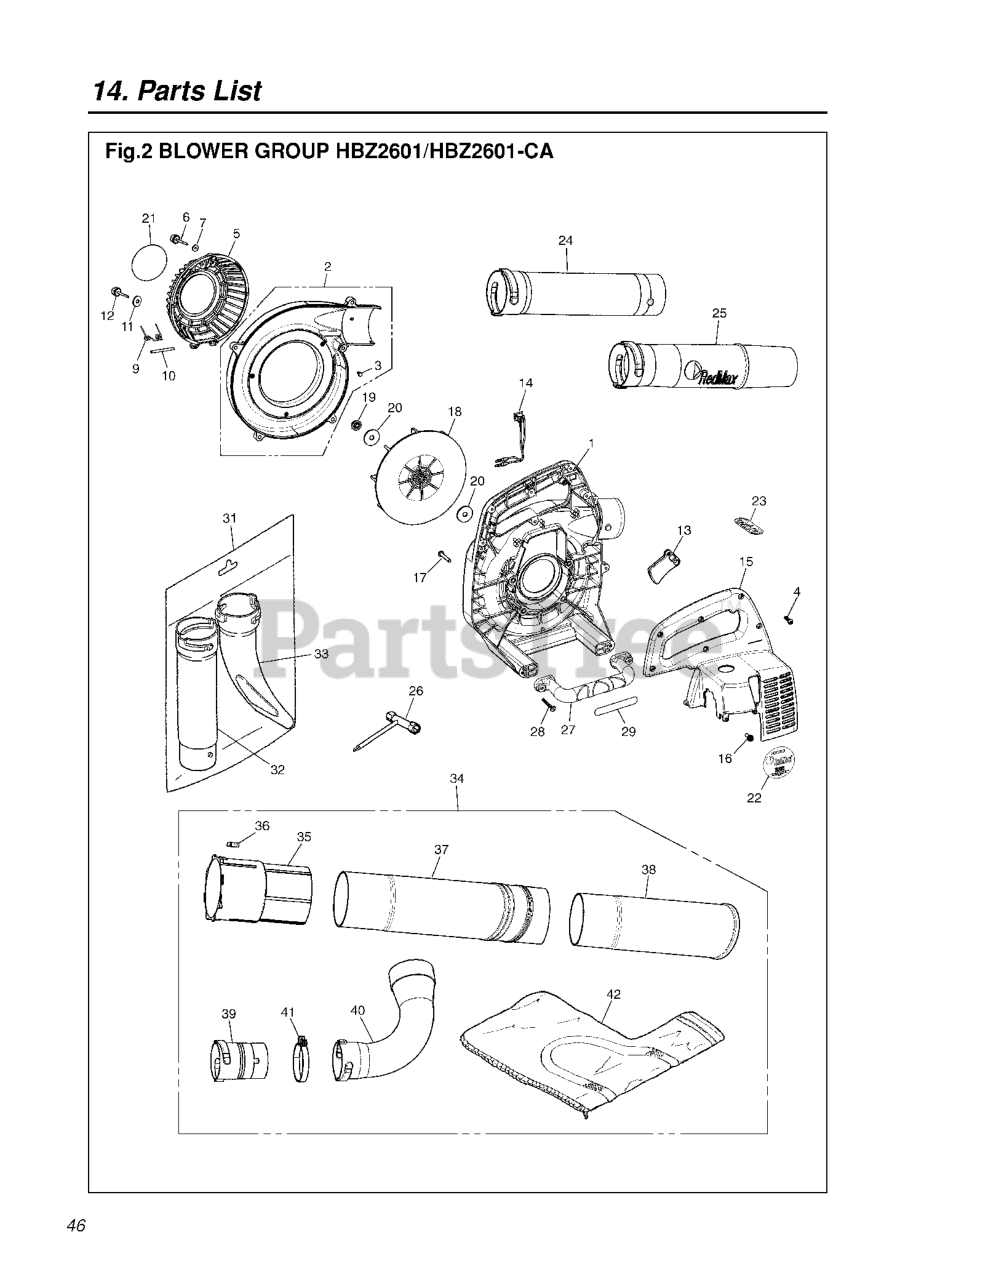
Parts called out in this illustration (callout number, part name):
1	VOLUTE CASE(R-55A1&681111110)
2	VOLUTECOVER(HBZ2600)T402211300
3	SCREW
4	SCREW, TORX (RPLS T4970-52001)
5	GUARD.NET
15	ENGINE COVER
19	NUT
23	Caution Label
24	PIPE STRAIGHT
25	PIPE.END
29	LABEL-A.HANDLE
31	FLAT NOZZLE KIT
32	PIPE STRAIGHT
33	FLAT NOZZLE
34	RedMax TBD
35	PIPE, A
39	EXTENSION (PIPE)
42	BAG, DUST
